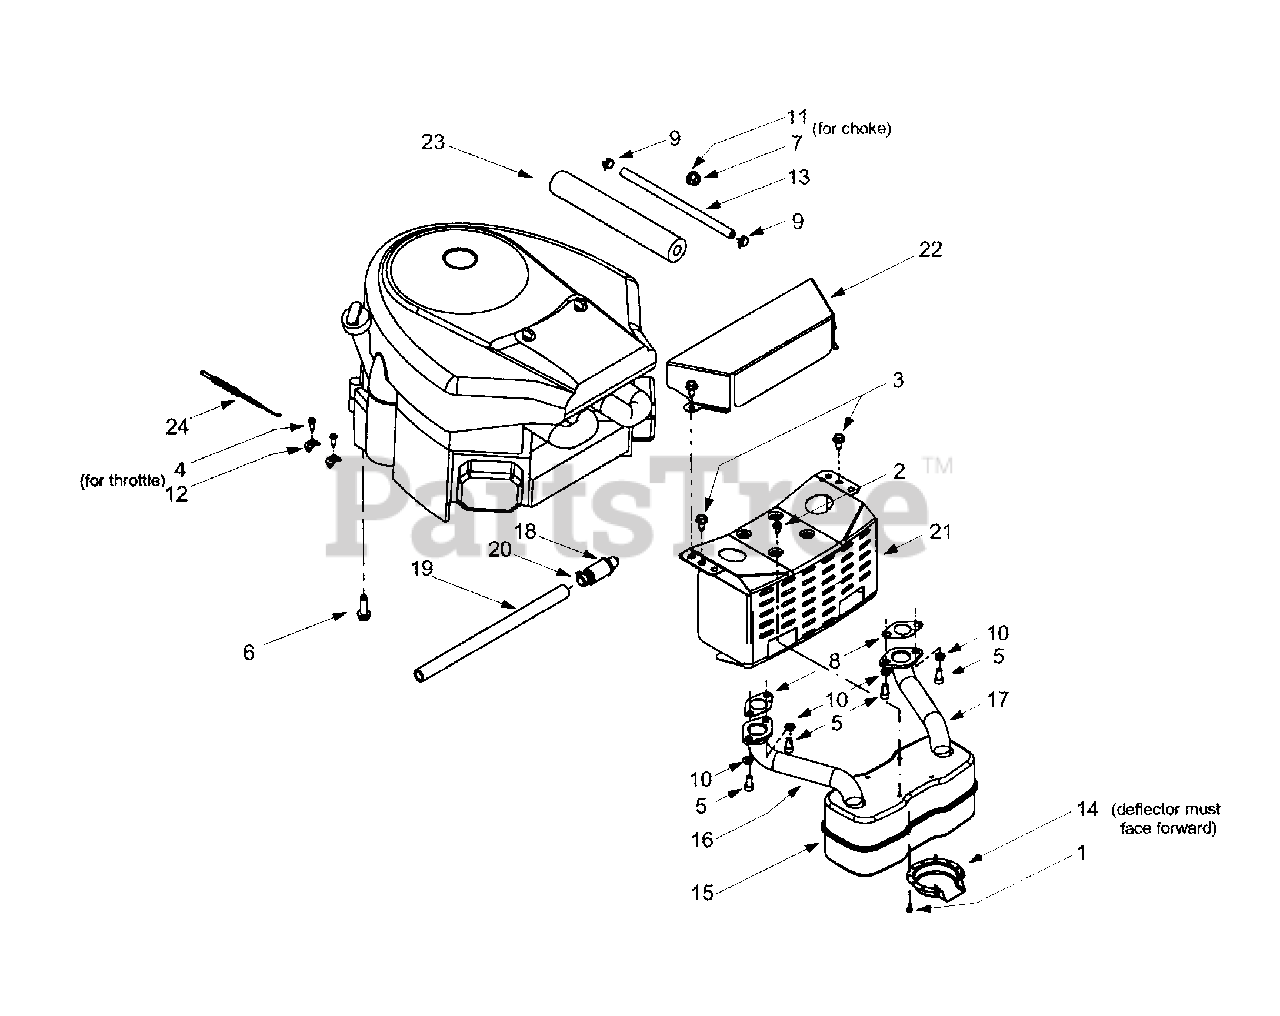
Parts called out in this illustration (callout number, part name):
1	Self-tapping Screw, #8-18 x.5
2	Self-tapping Screw, 1/4-20 x.5
3	Self-tapping Screw, 5/16-18 x .625
4	Screw, #10-32 x .625
5	Socket Cap Screw, 5/16-18 x .625
6	Self-tapping Screw, 3/8-16 x 1.25
7	Hex Nut, 3/8-16
8	Exhaust Gasket
9	Hose Clamp
10	Lock Washer, 5/16
11	Flat Washer, .406 x 875 x .059
12	Casing Clamp
13	Fuel Line Hose
14	Muffler Deflector
15	Muffler, Twin Inlet
16	RH Exhaust Pipe
17	LH Exhaust Pipe
18	Oil Drain Valve
19	Oil Drain Hose
20	Oil Drain Cap
22	Engine Heat Shield
23	Foam
24	Throttle Cable
